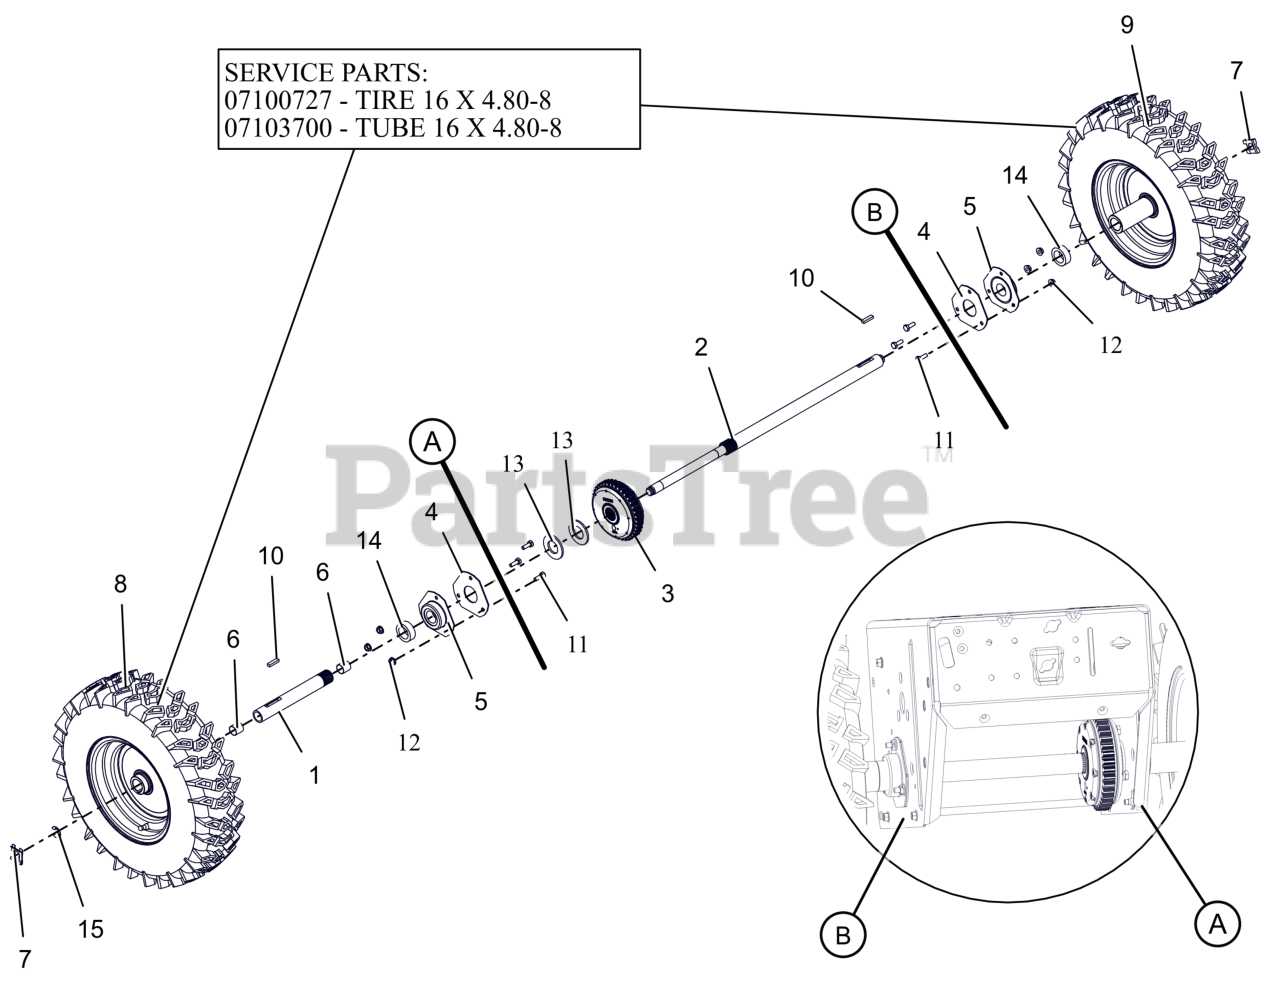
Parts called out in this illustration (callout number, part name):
1	AXLE, SHORT-AUTO W/BUSHINGS
2	AXLE, LONG-PRO AUTO DIFF
3	DIFFERENTIAL, AUTOMATIC
4	PLATE, BEARING SPACER
5	BRG-FLG 1.003/1.000 3 BOLT
6	BSHG-SLV .706X.764X.75 BRZ
7	CLIP, SNAP .625 DIA
8	TIRE/WHEEL,RH 16X4.8-8 DIFF T2
9	TIRE/WHEEL,LH 16X4.8-8 DIFF T2
9	SNOW TIRE, 16/4.80-8 K478 DIRECTIONAL
9	TIRE TUBE, 16X4.80/4.00-8 4 PLY TR13 STRAIGHT VALVE
10	KEY-RECT .25X.188X1.00
11	BLT, HEX .25-20X.75 G5 ZCC
12	NUT-LK-CTR-FLG .25-20 ZC120
13	WSHR, FLT 1.062X2.000X.134 ZCC
14	SPACER, PRO AXLE BEARING
15	RG-RTNG-EXT .625X.042
